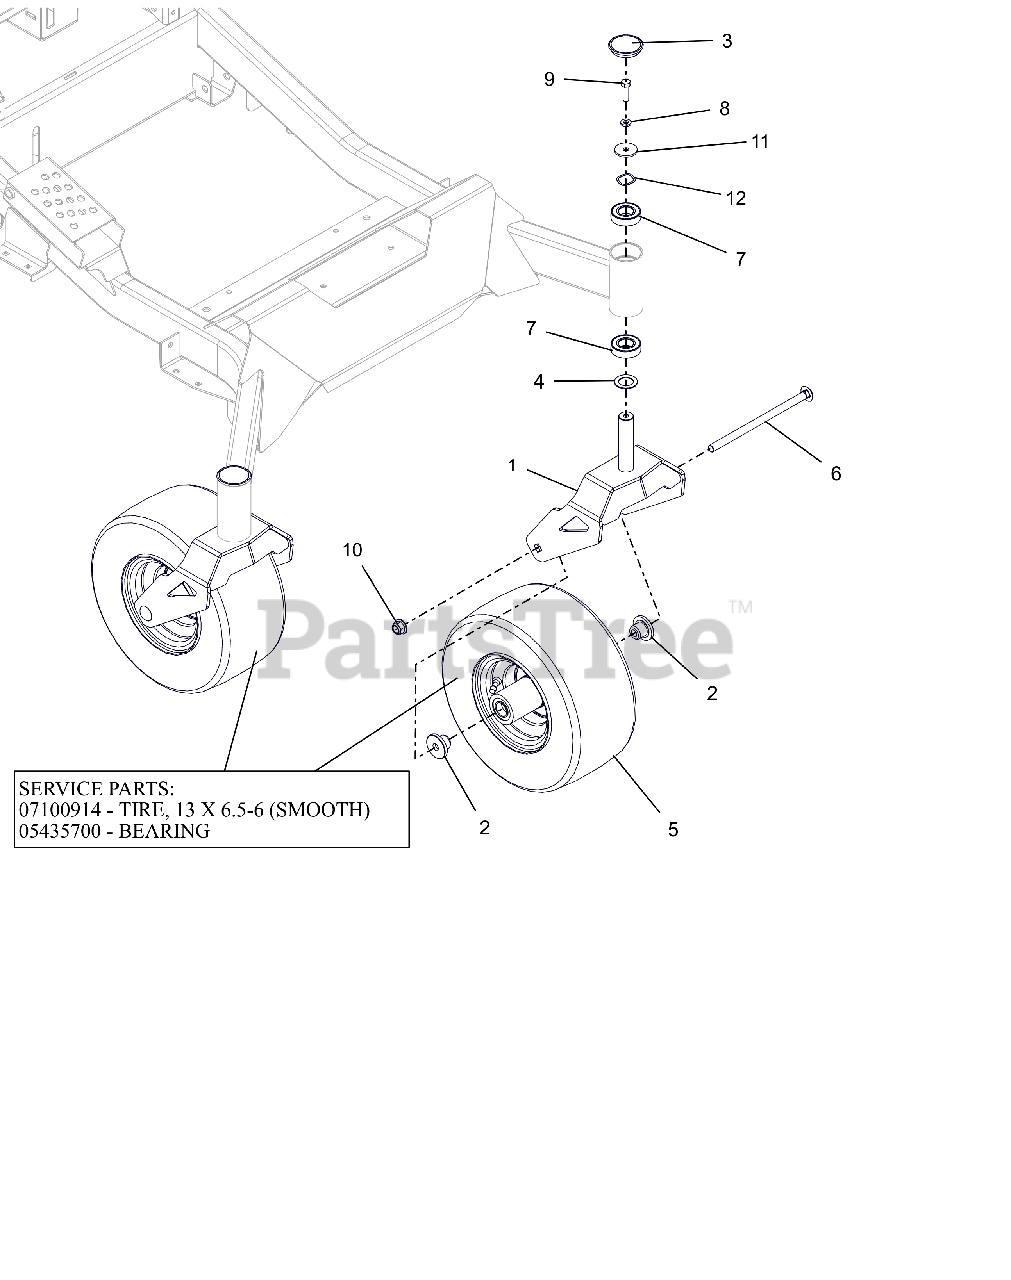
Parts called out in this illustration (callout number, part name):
1	WLDMT, HD CASTER FORK
2	SPACER, FRONT WHEEL
3	CAP, DUST
4	WSHR-HRD-THRS 1.007X1.542X.062
5	ASM, WHL/TIRE 13X6.50-6
5	TIRE, 13X6.50-6 SMOOTH
5	BRG, 25MM ID X 52MM OD X 15MM
6	BLT, RHSN .50-13X9.00 G5 ZCC
7	BRG,BALL 1.00X2.00X.563(1641)
8	WSHR, LK-HVY .375X.115 ZCC
9	BLT, HEX .38-16X1.25 G5 ZCC
10	NUT,NYL-FLG .50-13 GF ZCC
11	WSHR, FLT .380X1.50X.125 ZCC
12	WSHR-WAVE 1.0X1.25X.028 .145FH
